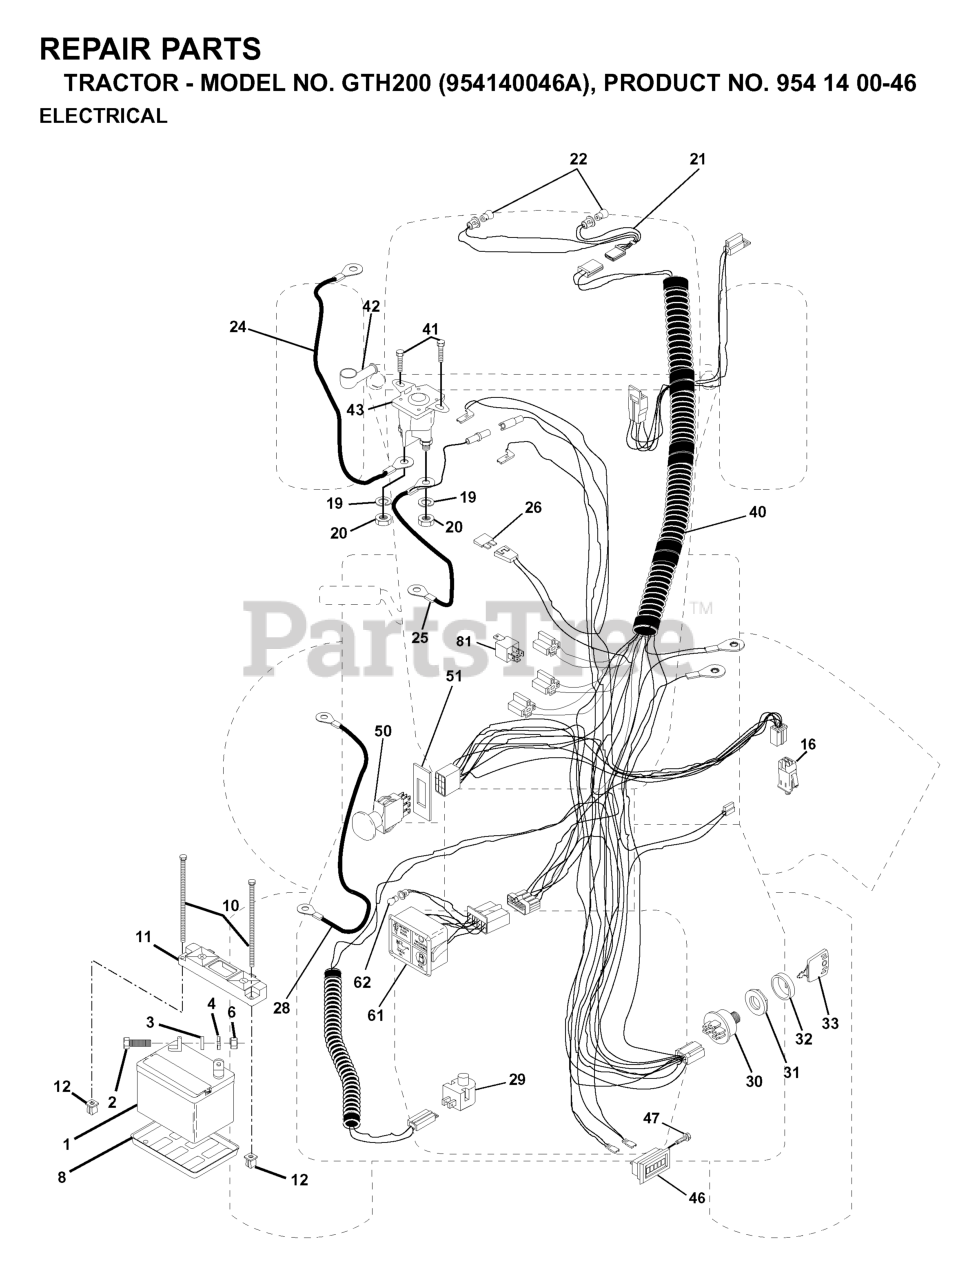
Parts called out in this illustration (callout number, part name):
1	BATTERY 12V .35 AMP
2	BOLT.HEX.1/4.X.3/4.DICHROMATE
3	LOCKWASHER
4	WASHER
6	NUT
8	BATTERY TRAY T
10	BOLT 1/4-20 X 7.5
11	BATTERY HOLDDOWN FRONT MOUNT
12	NUT, PUSH NYLON 1/4" BATTERY
16	SWITCH INTERLOCK
19	LOCKWASHER
20	NUT
21	HARNESS LIGHT SOCKET
24	CABLE, STARTER
25	CABLE, BATTERY
28	CABLE, GROUND
29	PLUNGER SWITCH (COLOR:OLIVE)
30	SWITCH.IGNITION.4.POSITION
31	NUT IGNITION
32	COVER SWITCH KEY
33	KEY.MOLDED.GENERIC
41	SCREW
42	TERMINAL COVER
43	SOLINOID
46	HOUR METER T
47	Screw 10-24 x 1/2 Black
50	SWITCH PTO 3 PDT
51	FRAME RETAINING RING
61	LIGHT PACKAGE
62	BULB LIGHT T
81	RELAY.ASSY.T
